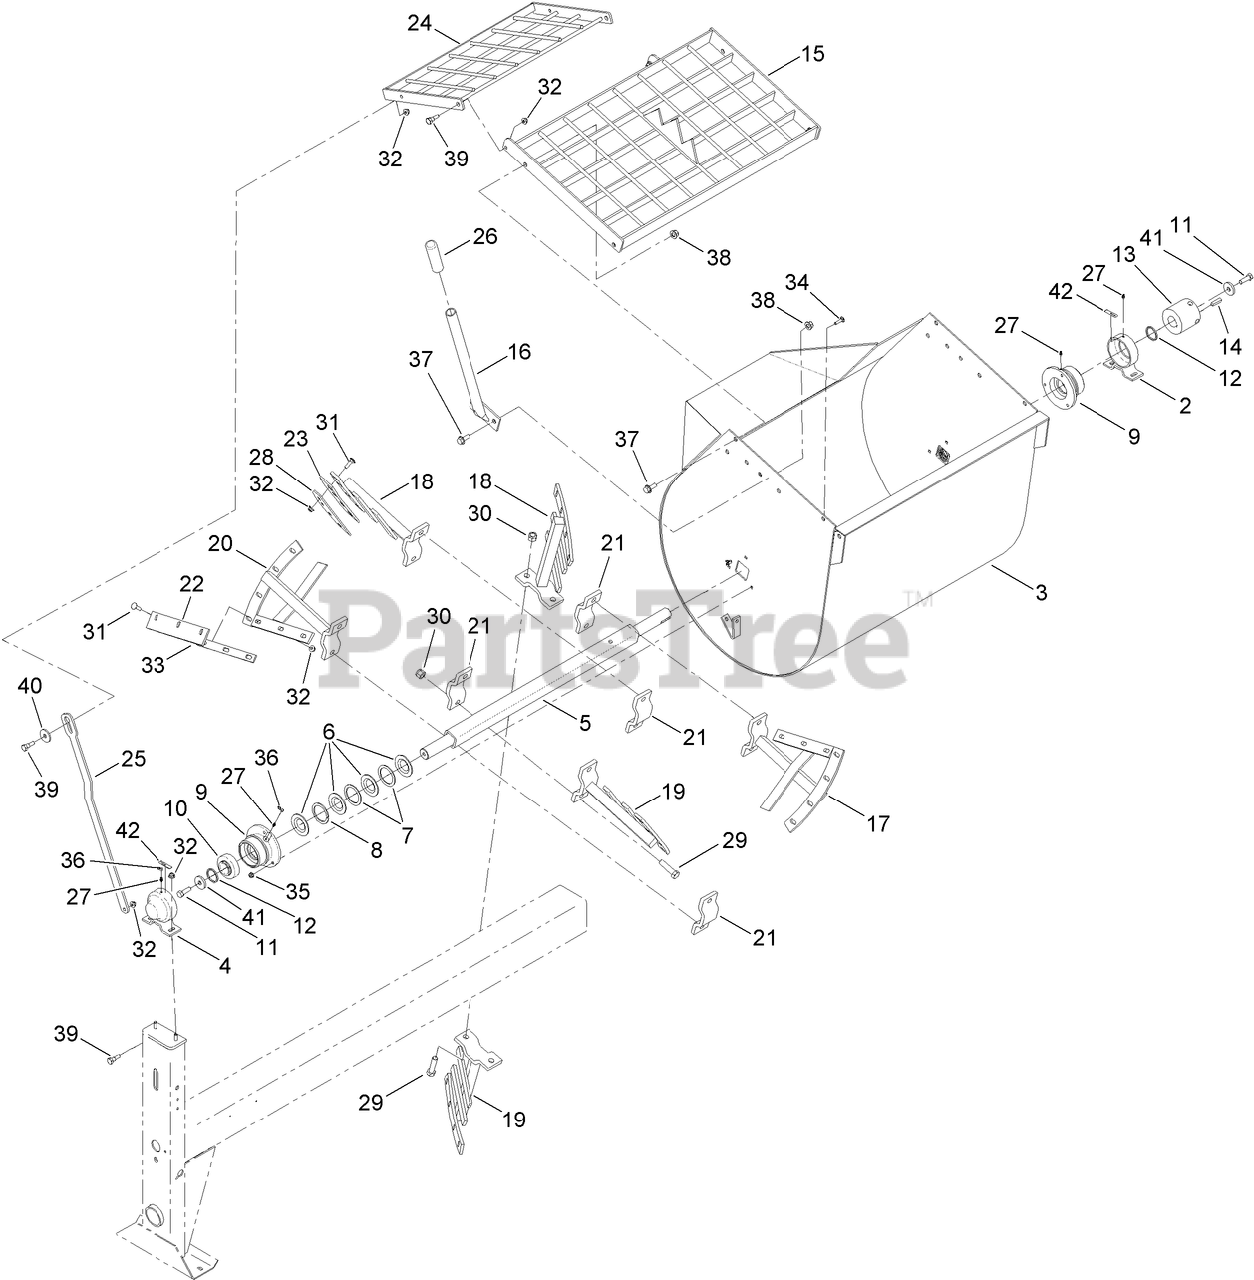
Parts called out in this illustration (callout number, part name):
2	TRUNNION
4	TRUNNION-CAPPED
5	SHAFT-DRUM
6	SEAL-DRUM
7	WASHER-FLAT
8	WASHER-SPLIT
9	HOUSING-BEARING
10	BEARING-BALL
11	SCREW-HH
12	SPACER-SHAFT, DRUM
13	COUPLING-SHAFT
14	KEY-SQUARE
16	HANDLE-DUMP
21	CLAMP-PADDLE
22	BLADE-RUBBER, SHORT
23	BLADE-RUBBER, LONG
24	GUARD-MOVEABLE
25	BAR-GUARD LIFT
26	GRIP-HAND
27	FITTING-GREASE
28	BAR-LONG, BACKER
29	SCREW-HH
30	NUT-LOCK, NI
31	BOLT-CARR
32	NUT-HF, NI
33	BAR-BACKER, SHORT
34	SCREW-CARR
35	NUT-HF, NI
36	CAP-PLUG
37	SCREW-HHF
38	NUT-LOCK
39	BOLT-SHOULDER
40	Washer-Thrust
41	WASHER-FLAT
42	DECAL-GREASE
